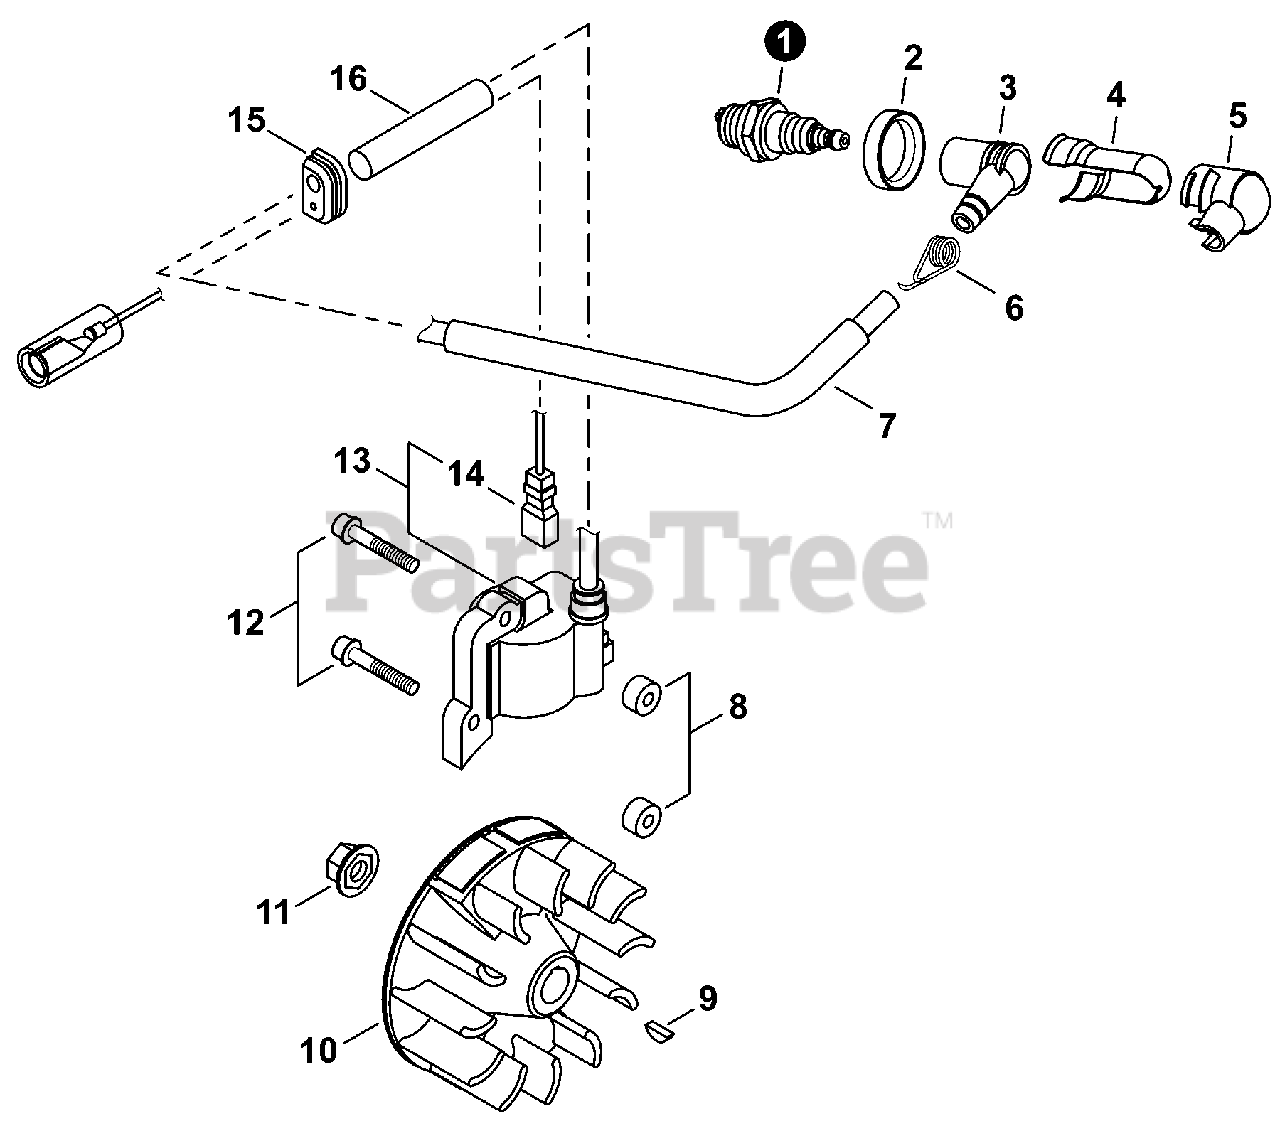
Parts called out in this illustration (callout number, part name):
1	SPARK PLUG - BMR6A
2	SEAL, SPARK PLUG
3	CAP, SPARK PLUG
5	COVER, CAP
6	TERMINAL, SPARK PLUG
7	TUBE, INSULATOR
8	INSULATOR 4.2×11×6
9	KEY, WOODRUFF 3×10
10	FLYWHEEL
12	BOLT 4×26
13	COIL ASSY, IGNITION
15	GROMMET
16	TUBE, IGNITION COIL
